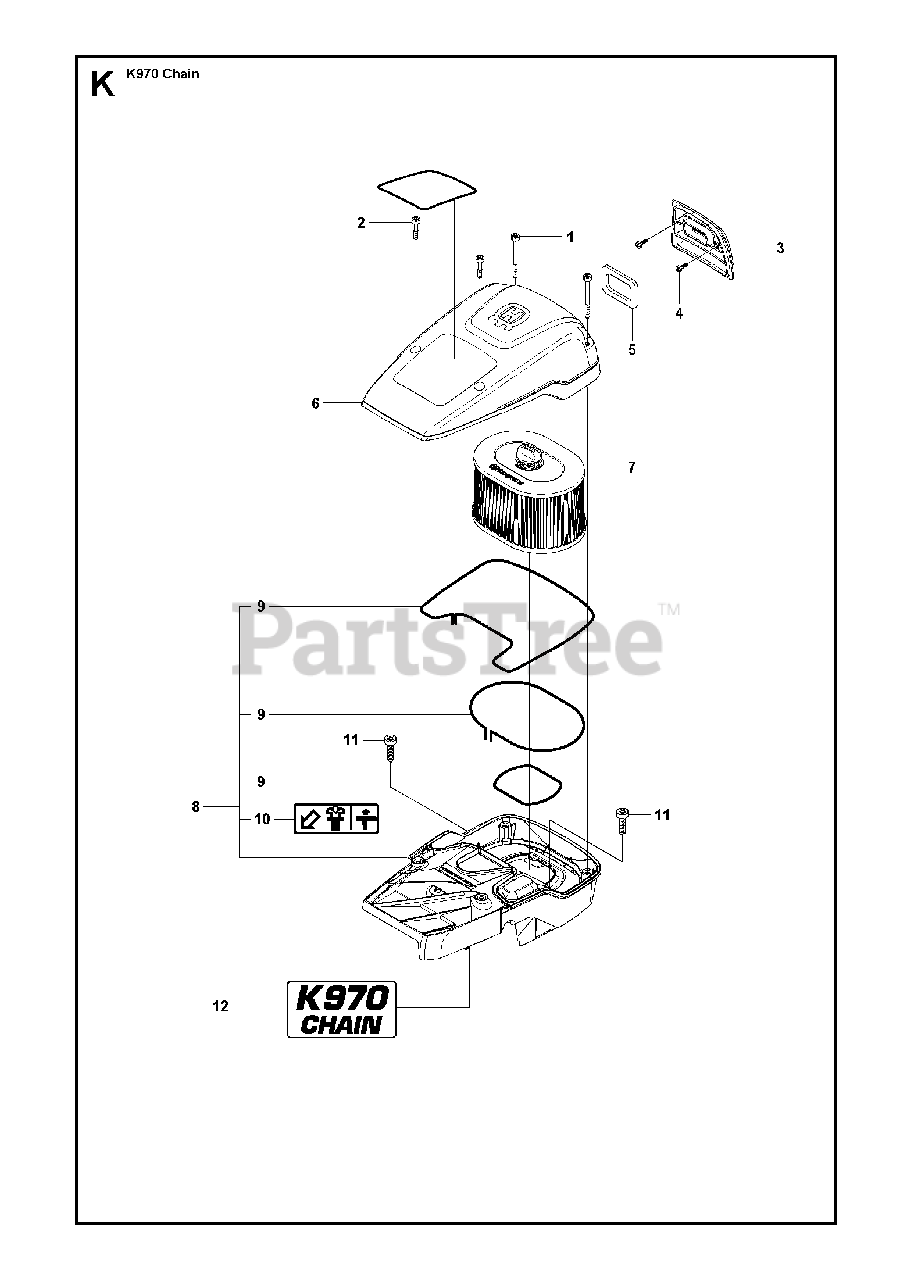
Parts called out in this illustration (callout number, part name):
1	SCREW ITXSCM
2	SCREW ITXSCM
4	SCREW CRPANT
7	AIR FILTER
8	CYLINDER COVERIncl. 9 - 10
9	SEALINGL=1,2 M. Cut to fit
11	SCREW ITXSCM
